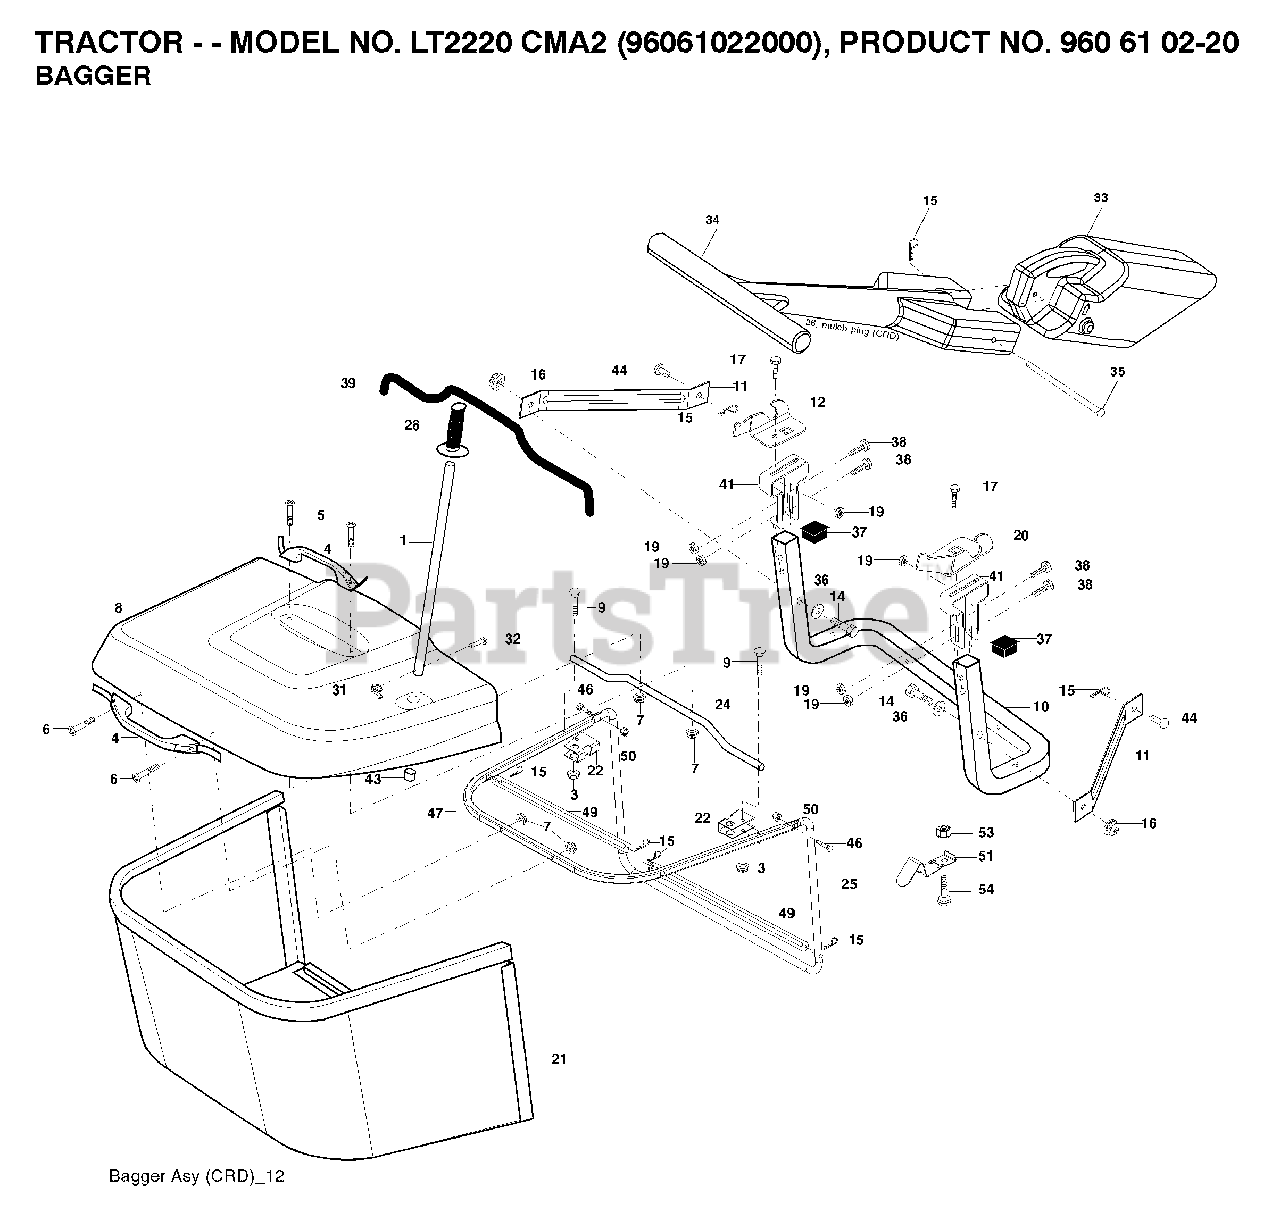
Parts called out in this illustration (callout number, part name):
1	TUBE HANDLE
3	NUT T
5	SCREW.PAN.HEAD
11	BRACKET
14	BOLT-HEX EAK
15	RETAINER-SPRNG RB
16	NUT LOCK FLG 3/8-16 UNC
17	BOLT
19	NUT LOCK HEX FLANGE 5/16-18
20	BRKT.PIVOT.RH.CRD
21	BAGGER.ASM.CRD.2007
22	BRACKET
24	TUBE
28	GRIP.HANDLE.BLACK
31	RETAINER CLIP
32	RIVET,DRILLED
33	MULCH PLUG, CTH150
35	PIN
38	BOLT.5/16-18X2.5
41	BRKT, BAGGER
43	PLUG, TUBING END
46	BOLT.CARRIAGE.5/16-18
50	NUT.71038.31-18.HEX.NYLOCK
53	NUT
54	BOLT
